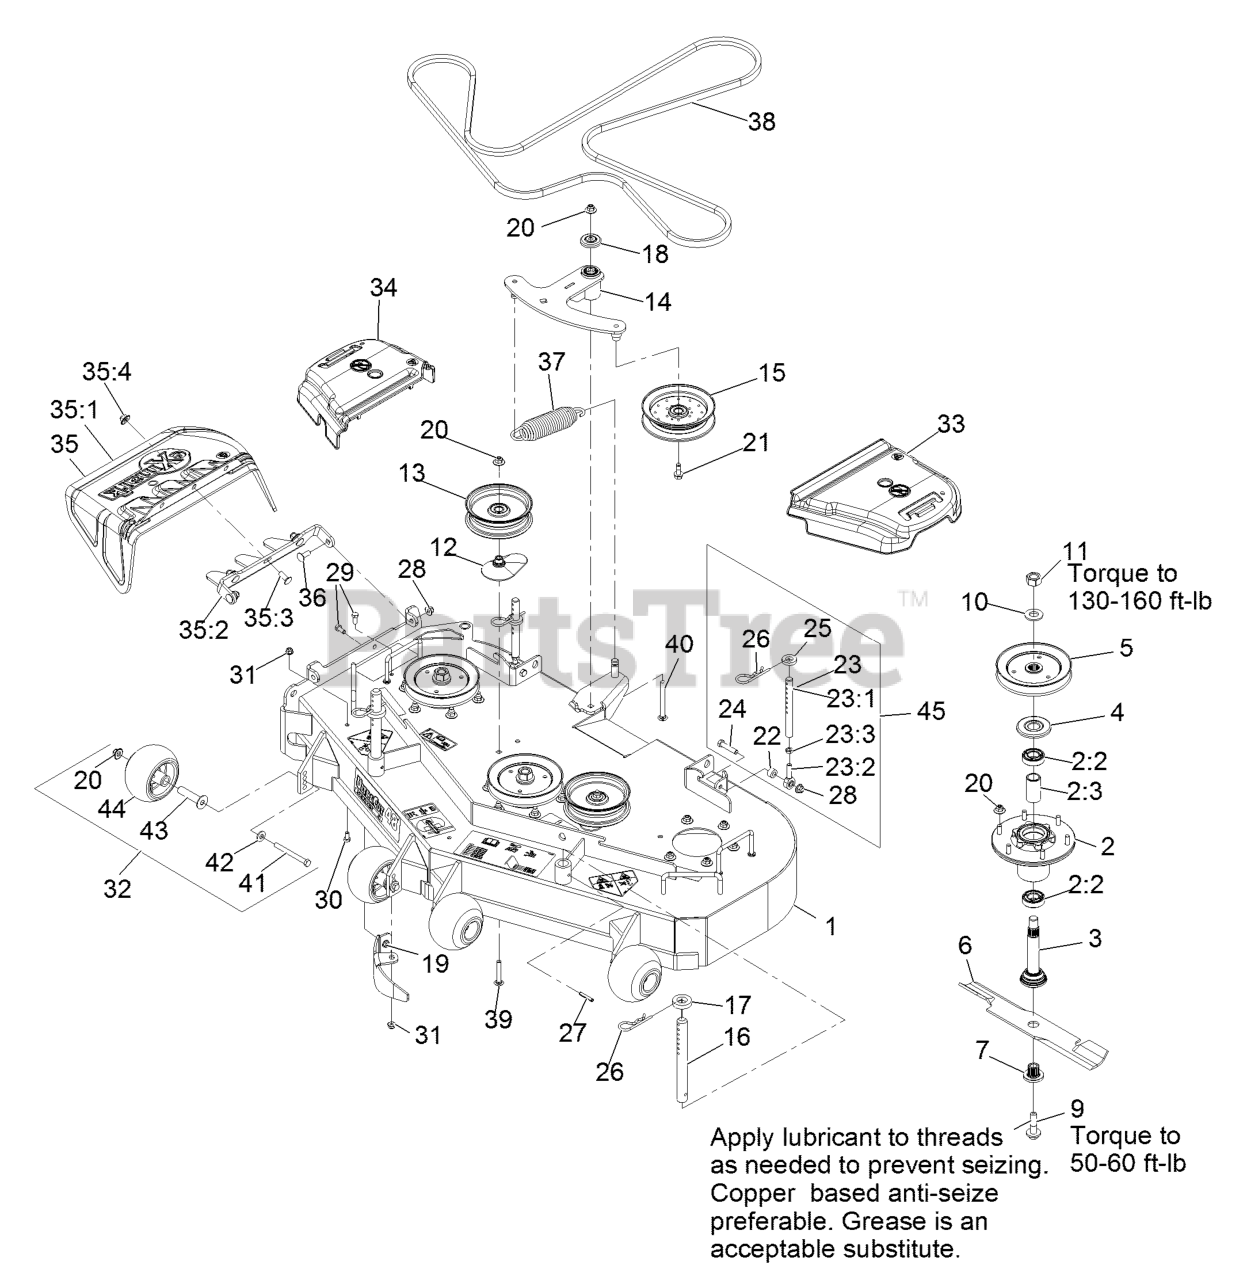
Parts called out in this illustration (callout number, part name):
1	ASM, DECK 48" W/DECALS
2	ASM-CUTTER HSG WITH BEARINGS
2:2	BEARING-BALL
2:3	SPACER-BEARING
3	ASM-SPINDLE AND SEAL
4	GUARD,BEARING TOP .989
5	SHEAVE,BLADE DRIVE 5.90
7	BUSHING,SPLINED
9	SCREW,SEMS 1/2-20 X 2.19
11	NUT-HEX
12	SPACER-PULLEY
13	IDLER-PULLEY, FLAT
14	ASM, DECK IDLER
16	ROD,DECK SUPPORT
17	SPACER-DECK SUPPORT
18	GUARD-TOP
19	BAFFLE, DOGLEG
20	Nut-Nyloc 3/8-16 Flg
21	SCREW-HFH
23:1	LINK,SUPPORT
23:2	BALLJOINT
23:3	NUT-HJ
24	SCREW-HH
26	PIN,HAIR COTTER
28	NUT-HF, NI
29	SCREW-HH
30	SCREW-HH
31	NUT-HF, NI
32	KIT, ANTI-SCALP ROLLER
33	COVER-BELT, LH
34	COVER-BELT, RH
35	ASM, DISCHARGE CHUTE
35:1	CHUTE,DISCHARGE
35:2	BRACKET, DISCHARGE CHUTE
35:3	SCREW-CARR
35:4	Nut-Nyloc 3/8-16 Flg
36	SCREW-CARR
37	SPRING-EXTENSION
38	BELT, DECK
39	BOLT-CARR, SHORT NECK
40	SCREW-CARR
41	SCREW-HH 3/8-16 X 3 3/4 GR 8
42	WASHER-BELLEVILLE
43	AXLE, ROLLER
44	ROLLER-SCALP, ANTI
45	KIT,SUPPORT LINK W/PIN
